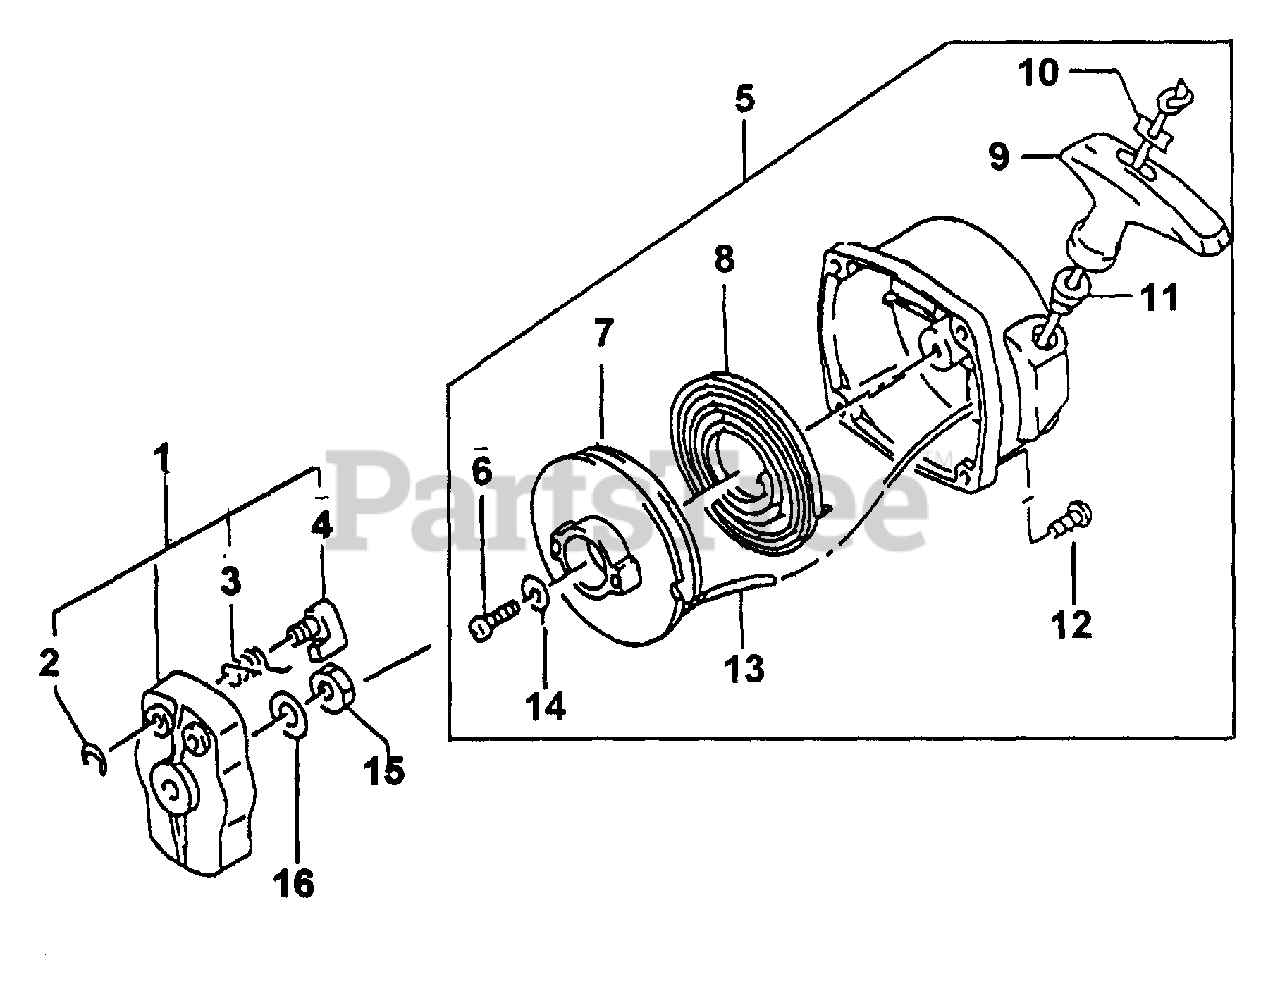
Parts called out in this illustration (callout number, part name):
1	PULLEY ASSY.
2	SNAP RING
3	SPRING, RETURN
5	STARTER ASSY.
7	STARTER REEL
8	SPRING, RECOIL
10	PLATE, ROPE
11	ROPE GUIDE
12	SCREW
15	NUT
